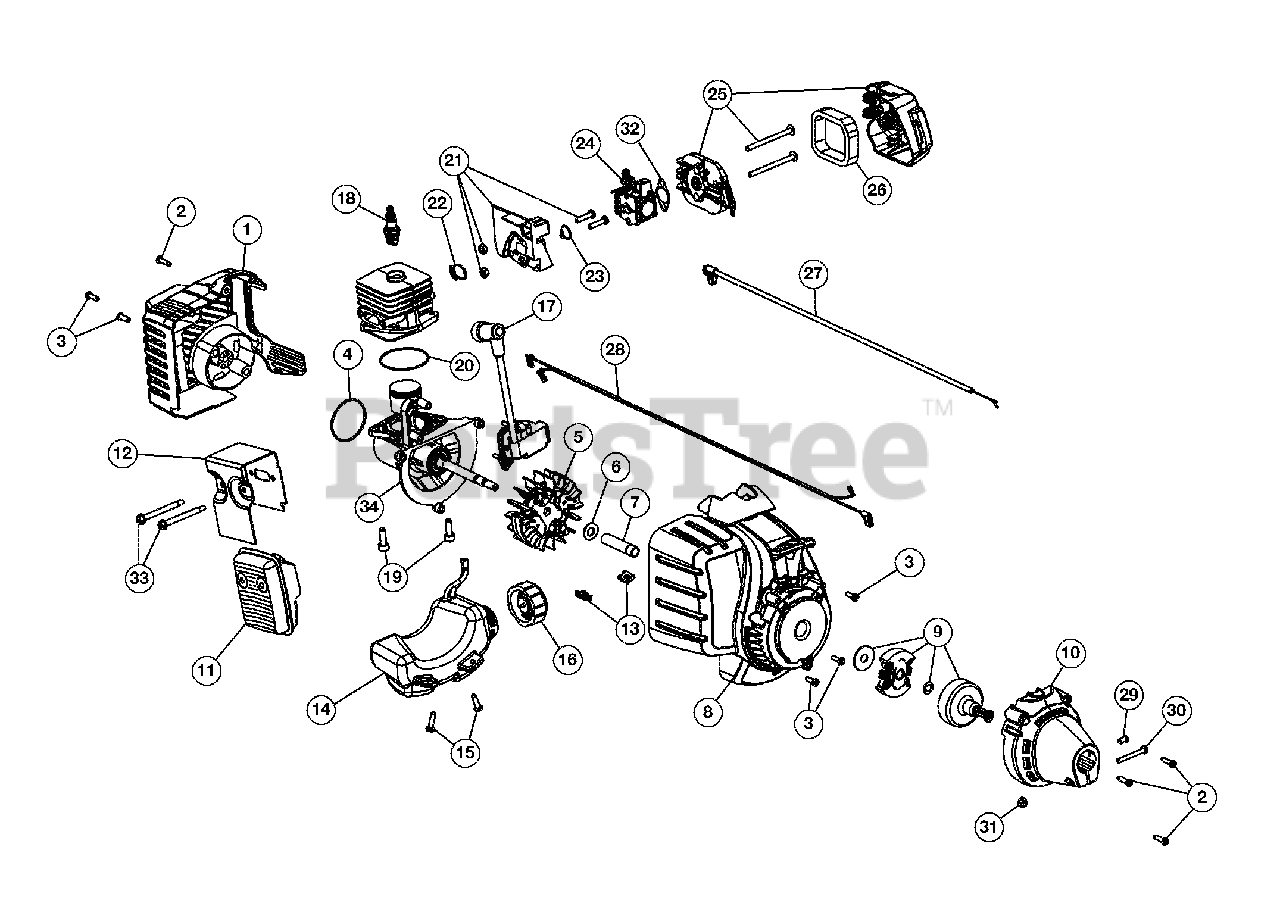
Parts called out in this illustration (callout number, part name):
1	Rear Cover Assembly (Incl. 2 & 3)
2	Cover Screw
3	Housing Screw
4	O-Ring
5	Flywheel Assembly
6	Washer
7	Spacer
8	Starter Housing (Incl. 3 & 13)
9	Clutch Assembly
10	Clutch Cover (Incl. 2)
11	Muffler Assembly (Incl. 12 & 33)
12	Muffler Gasket
13	U-shaped Nut
14	Fuel Tank Assembly (Incl. 15 & 16)
15	Tank Screw
16	Fuel Cap
17	Module Assembly
18	Spark Plug
19	Crankcase Bolt
20	Crankcase O-Ring
21	Insulator Assembly (Incl. 22 & 23)
22	Insulator O-Ring
23	Carburetor O-Ring
24	Carburetor
25	Aircleaner Cover Assembly (Incl. 26)
26	Aircleaner Filter
27	Throttle Cable
28	Lead Wires
29	Anti-rotation Screw
30	Clamp Screw
31	Clamp Nut
32	Air Cleaner Gasket
33	Muffler Screw
34	Short Block Assembly (Incl. 4-7 & 17-20)
